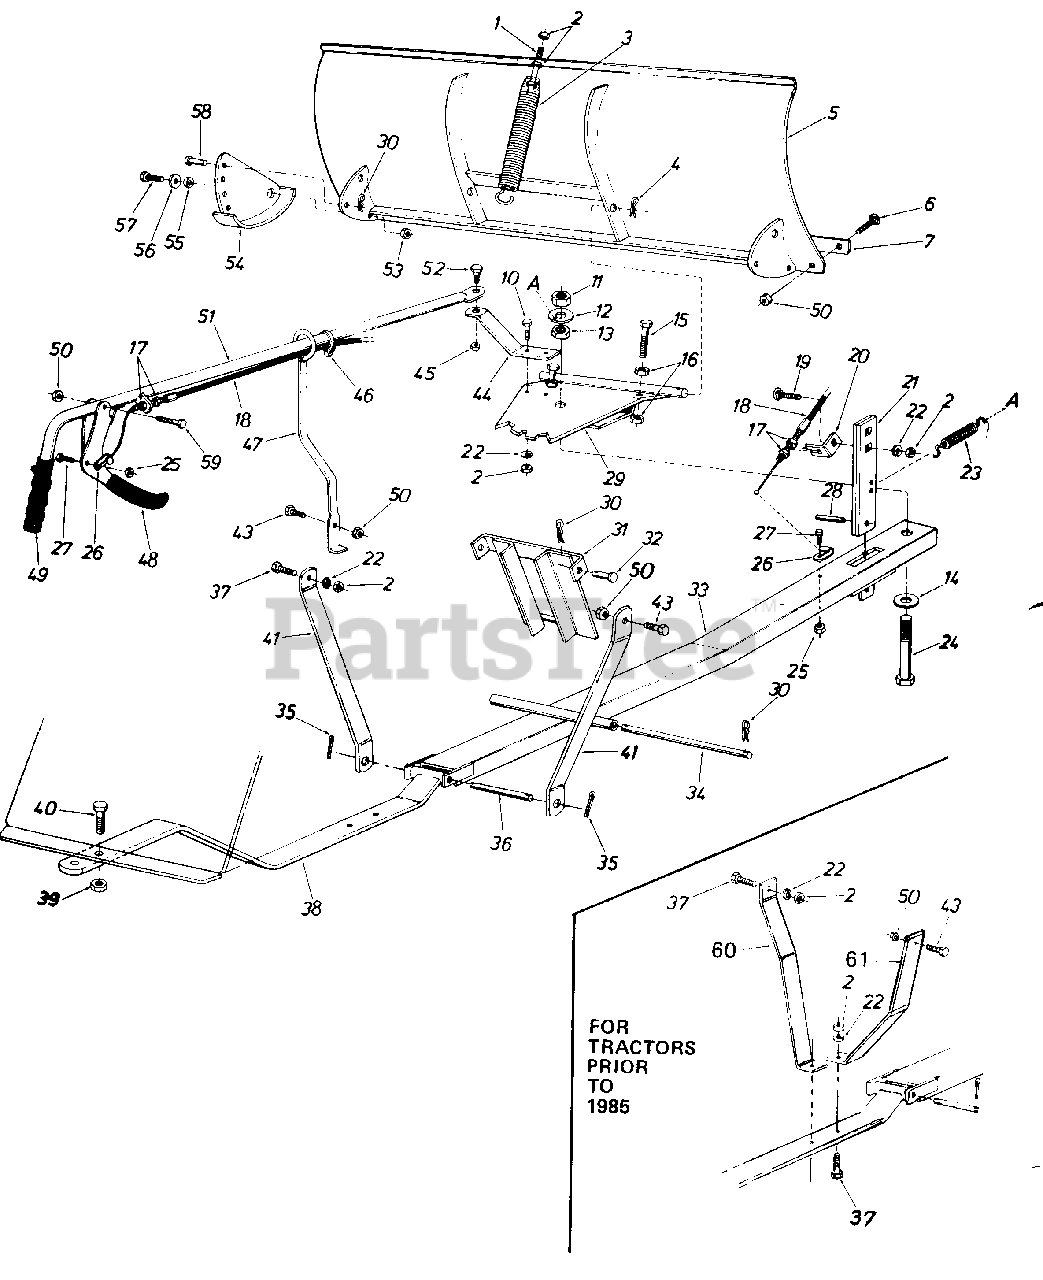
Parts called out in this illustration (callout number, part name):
1	Hex Scr. 3/8-16 x 4.50" Lg.*
2	Hex Nut 3/8-16 Thd.*
3	Blade Adjustment Spri ng
4	Hair Pin Cotter 5/32" Dia.
5	48" Blade Ass'y.
6	Carriage Bolt 5/16-18 x.75" Lg.*
7	Wear Plate 48"
10	Hex Scr. 3/8-16 x 1.00" Lg.*
11	Hex L.-Nut 3/4-10 Thd.
12	Fl.-Wash..810" I.D. x 2.00" O.D.
13	Hex Jam Nut 3/4-10 Thd.*
14	Fl.-Wash..810" I.D. x 2.00" O.D.
15	Hex Scr. 1/2-13 x 2.00" Lg.*
16	Hex Nut 1/2-13 Thd.*
17	Hex Jam Nut 5/16- 24 Thd.*
18	Control Cable Ass'y.
19	Carriage Bolt 3/8-16 x 1.25" Lg.*
20	Cable Guide Bracket
21	Angle - Lock Bar
22	L.-Wash. 3/8" Scr.*
23	Angle Lock Spring
24	Hex Scr. 3/4-10 x 4.00" Lg.
25	Hex L.-Nut 1 /4-20 Thd.
26	Clevis Lanyard F itti ng
27	Hex Scr. 1/4-20 x .75" Lg.*
28	Spring Pin Spirol 1/4" Dia. x 1.00" Lg.
29	Pivot Plate Ass'y.
30	Hair Pin Cotter 3/32" Dia.
31	Guide Bracket Ass'y.
32	Clevis Pin 1/2" Dia. x 1.00" Lg.
33	Push Bar Ass'y.
34	Lift Shaft
35	Cotter Pin 5/32" Dia. x 1.00" Lg.*
36	Pivot Pin
37	Hex Scr. 3/8-16 x 1.25" Lg.*
38	Hanger Bracket Ass'y.
39	Hex L.-Nut 5/8-11 Thd.
40	Hex Scr. 5/8-11 x 1.50" Lg.*
41	Hanger Link
43	Hex 5/16-18x 1.00" Lg.*
44	Blade Pivot Bracket
45	Hex L.-Nut 3/8-16 Thd.
46	Nylon Cable Tie
47	Tube Guide Ass'y.
48	Clutch Grip Ass'y.
49	Grip - 3/4" Handle
50	Hex L-Nut 5/16-18 Thd.
51	Tube Handle Ass'y.
52	Shld. Scr. - Special 3/8-16 Thd.
53	Hex L.-Nut 3/8-16 Thd.
54	Skid Assembly
55	Spacer
56	Fl.-Wash..385" I.D. x 1.00" 0. D .
57	Hex Scr. 3/8-16 x .75" Lg.*
58	Clevis Pin 5/16" Dia. x.75" Lg.
59	Hex Scr. 5/16-18 x 1.50" Lg.
60	Mounting Brkt.-L.H.
61	Mounting Brkt.-.H.
